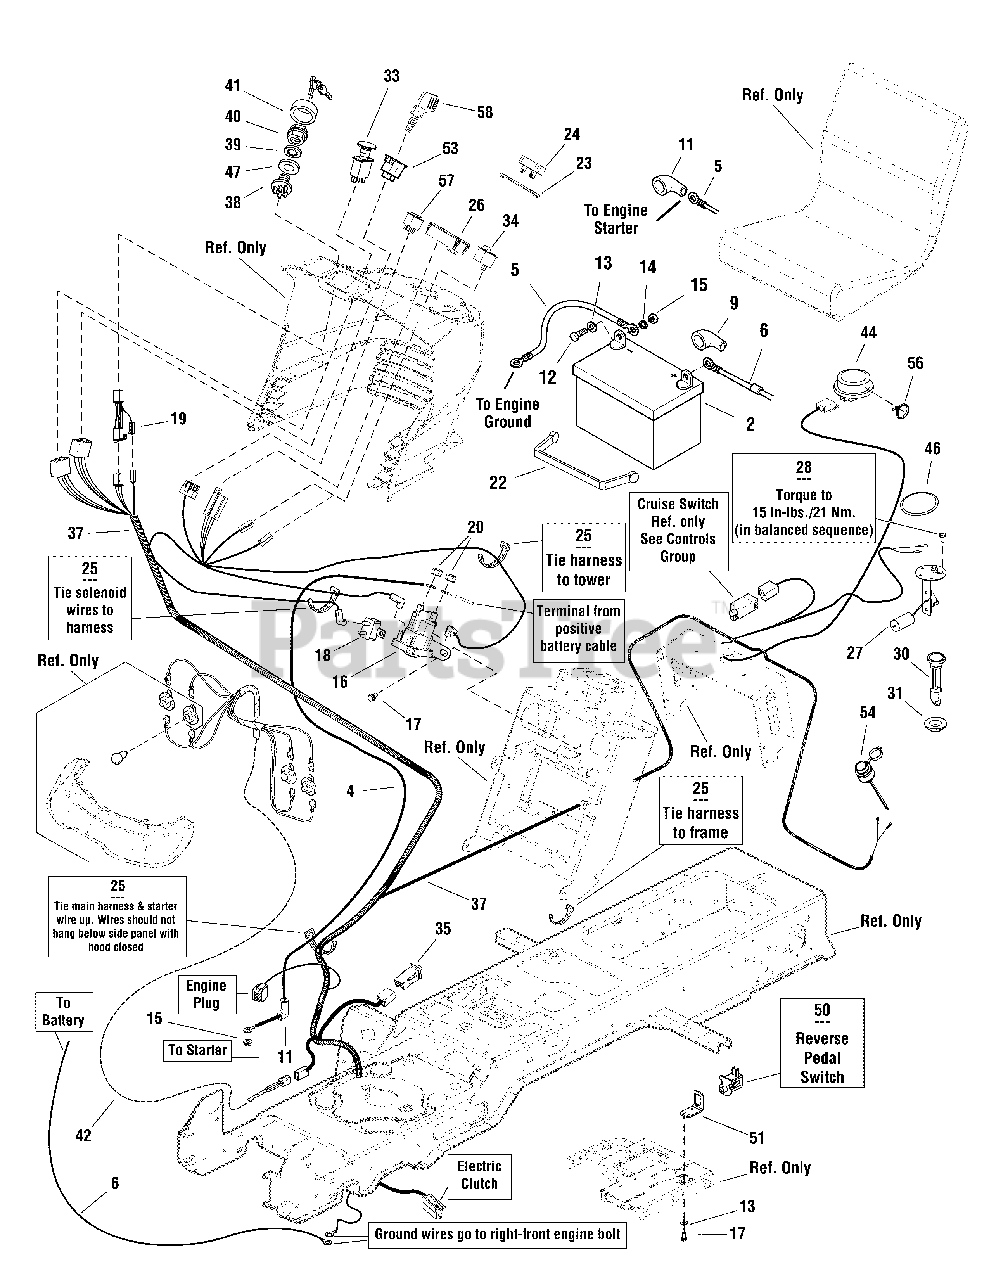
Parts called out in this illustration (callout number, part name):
2	BATTERY, 12 Volt
4	CABLE, #6 x 8" Long, Ring Terminals
5	CABLE, #6 x 25" Long, Ring Terminals
6	CABLE, #6 x 26" Long, Ring Terminals
9	BOOT, Insulator Battery Terminal
11	BOOT, Insulator Battery Terminal
12	SCREW, 1/4-20 x 3/4
13	WASHER, 1/4
14	LOCKWASHER, 1/4
15	NUT, 1/4-20
16	SOLENOID
17	SCREW, Taptite, 1/4-20 x 1/2
18	CIRCUIT BREAKER
19	HARNESS, Jumper
20	NUT, Locking, KEPS, 5/16-24
22	STRAP, Battery
23	PLUG, Dash
24	HOURMETER, WIth Alarms
25	TIE, Cable
26	INSTRUMENT PANEL
27	SENDER, Fuel
28	SCREW, Pan Head, #10-32 x 1/2
30	GAUGE, Fuel
31	GROMMET
33	SWITCH, PTO
34	SWITCH, Headlight
35	SWITCH, Pedal
37	HARNESS, Main
38	SWITCH, Ignition, Use Key #1737836YP
39	LOCKWASHER, 5/8
40	NUT, Hex Flange, 5/8-32
41	COVER, Switch
42	HARNESS, Headlight
44	SWITCH, Seat
46	PLUG, 3"
47	WASHER, Shim
50	SWITCH, Snap
51	MOUNTING BRACKET, Switch
53	MODULE, No Mow
54	OUTLET, 12 Volt
56	TIE, Self Locking
57	SWITCH, EHOC
58	KEY, RMO, Plastic Yellow
